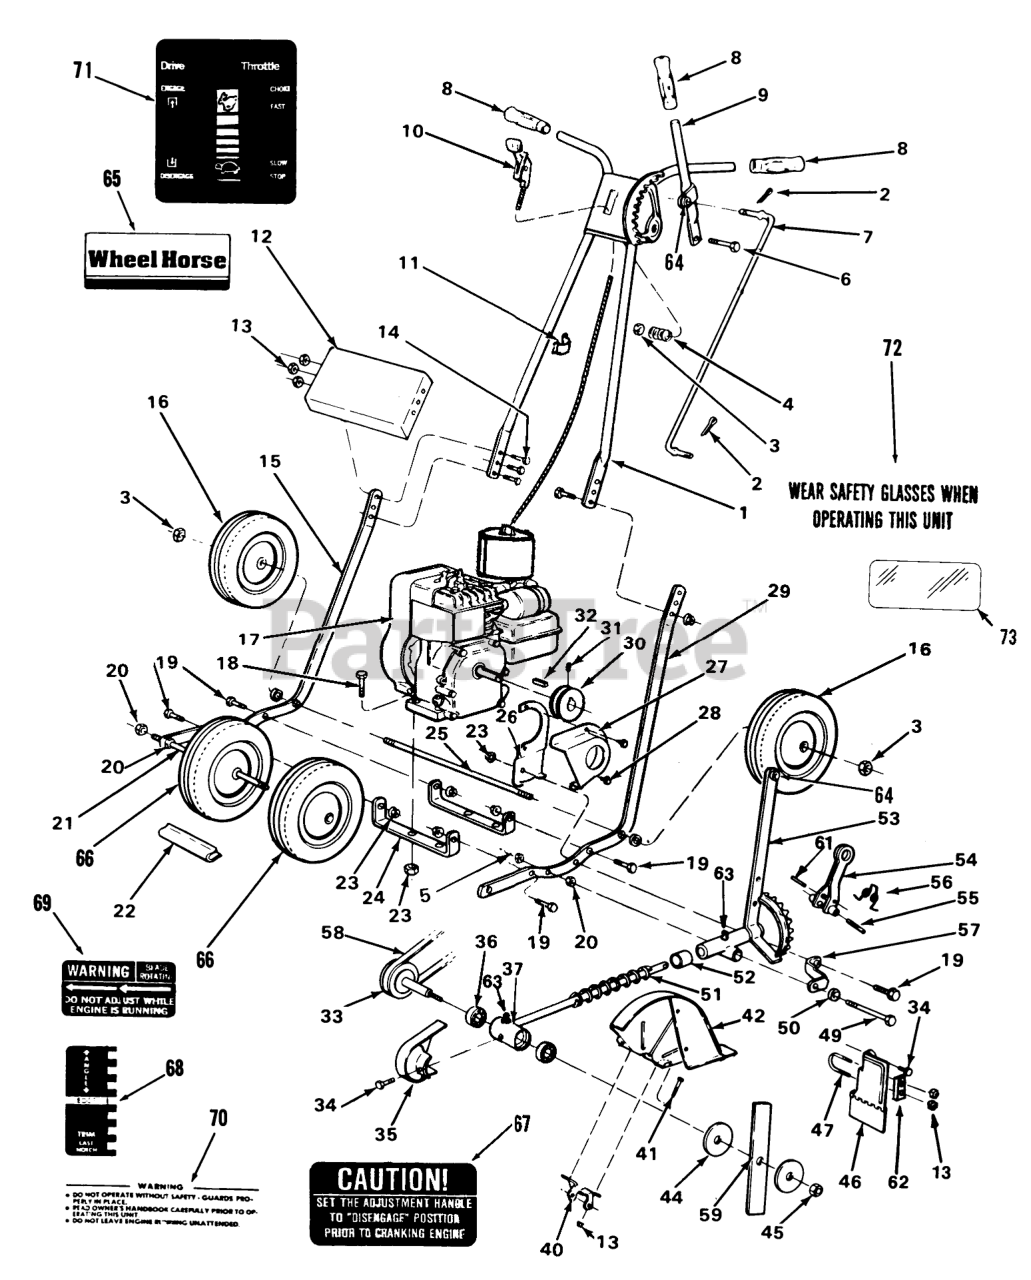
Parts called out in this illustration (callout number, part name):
1	Handle
2	Cotter Pin 1/8 x 1/2
3	NUT-JAM(7/16-14)
4	SPRING
5	Plastic Washer
6	Hex Bolt 7/16-14 x 2
7	Clutch and Depth Rod
9	Clutch and Depth Lever
10	CONTROL THROTTLE
11	CLIP THROTTLE CABLE
12	Handle Cross Brace
13	Hex Nut 1/4-28
14	Hex Bolt 1/4-28 x 7/8
15	Frame RH
16	Rear Wheel Assembly (includes (1) 112284 Rim,(1) 112283 Tire, (1) 112282 Inside Bearing, (1) 112281 Outside Brg & (1) 112285 Hubcap)
17	Engine-B & S Model 80202 type 1765
18	Hex Bolt 5/16-24 x 1-1/2
19	Hex Bolt 5/16-24 x 7/8
20	Hex Nut 7/16-14
21	Front Axle
22	SPACER FRONT WHEEL
23	Hex Nut 5/16-24
24	Frame Crossmember
25	Rear Axle
26	Engine Pulley Guard Bracket
27	GUARD ENGINE PULLEY
28	SCREW SPECIAL
29	FRAME LH
30	PULLEY ENGINE
31	Set Screw 5/16-24 x 5/16
32	Key 3/16 x 3/16 x 5/8
33	ASSY PULLEY & SHAFT
34	Screw
35	Cutterhead Pulley Guard
36	Cutterhead Bearing
37	Head Mandrel
40	CLAMP BLADE GUARD
41	Hex Bolt 1/4-28 x 1 1/2
42	GUARD BLADE
44	WASHER FRICTION
45	NUT-6
46	Debris Sweep Deflector
47	U-Clamp
49	Pivot Bolt 7/16-14 x 3-1/4
50	WASHER
51	Head Recoil Spring
53	Cutterhead Body
54	Angle Shifting Lever
55	ROLL PIN 5/16 X 2
56	Spring
57	Cutterhead Brace
58	BELT DRIVE
59	Cutting Blade
60	SPIROL ROLL PIN
62	U-Clamp Spacer
63	Grease Zerk
64	BEARING
65	5-Speed Decal
66	Front Wheel Assembly (includes (1) 112329 Rim, (1) 112283 Tire, (2) 112282 Wheel Bearings)
67	DECAL CAUTION
68	DECAL TRIM
69	Decal-Blade Warning
70	DECAL OPERATION
71	Decal-Throttle
72	DECAL SAFETY GLASSES
73	PUSH SWITCH WO
